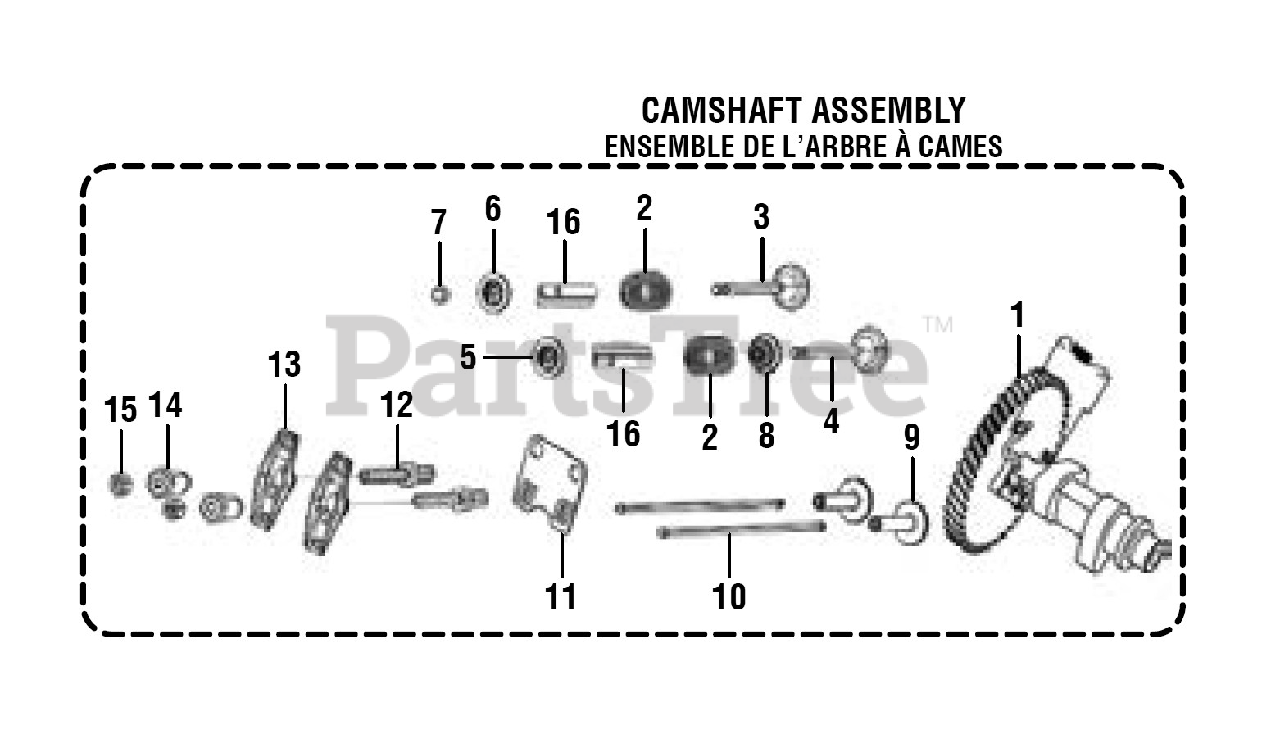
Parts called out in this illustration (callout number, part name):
1	Camshaft Assembly
2	Valve Spring
3	Exhaust Valve
4	Intake Valve
5	Valve Spring Seat
6	Retaine, Exhaust Valve
7	Valve Rotator
8	Seal Guide
9	Valve Tappet
10	Valve Lifter
11	Lifter Stop Plate Assembly
12	Valve Adjusting Bolt
13	Valve Rocker
14	Valve Adjusting Nut
15	Valve Lock Nut
16	Valve Lock Clip
